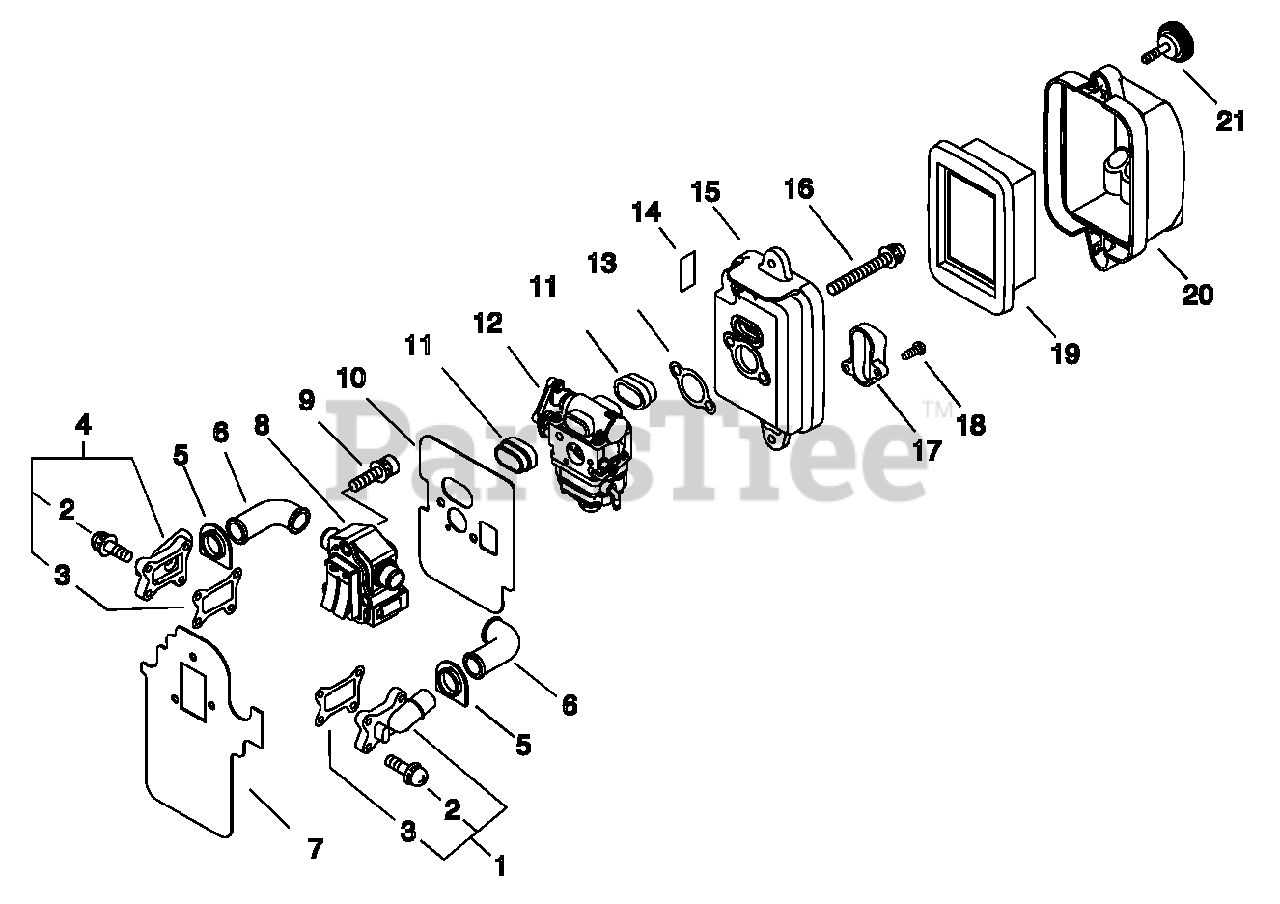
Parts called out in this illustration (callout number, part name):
1	REED VALVE KIT - INNER
2	SCREW - 4
3	GASKET, INTAKE
4	REED VALVE KIT - OUTER
5	GROMMET
6	HOSE, AIR
7	GASKET, INTAKE
8	VALVE ASSY
9	SCREW - 5X35
10	GASKET, INTAKE
11	BOOT, CONNECTOR
12	CARBURETOR WLA-1
13	GASKET, INTAKE
14	LABEL - CHOKE
15	CASE, AIR FILTER
16	SCREW - 5X65
17	FIXTURE, CLEANER
18	SCREW - 4X14
19	FILTER, AIR
20	COVER, AIR FILTER
21	KNOB, FASTENER
